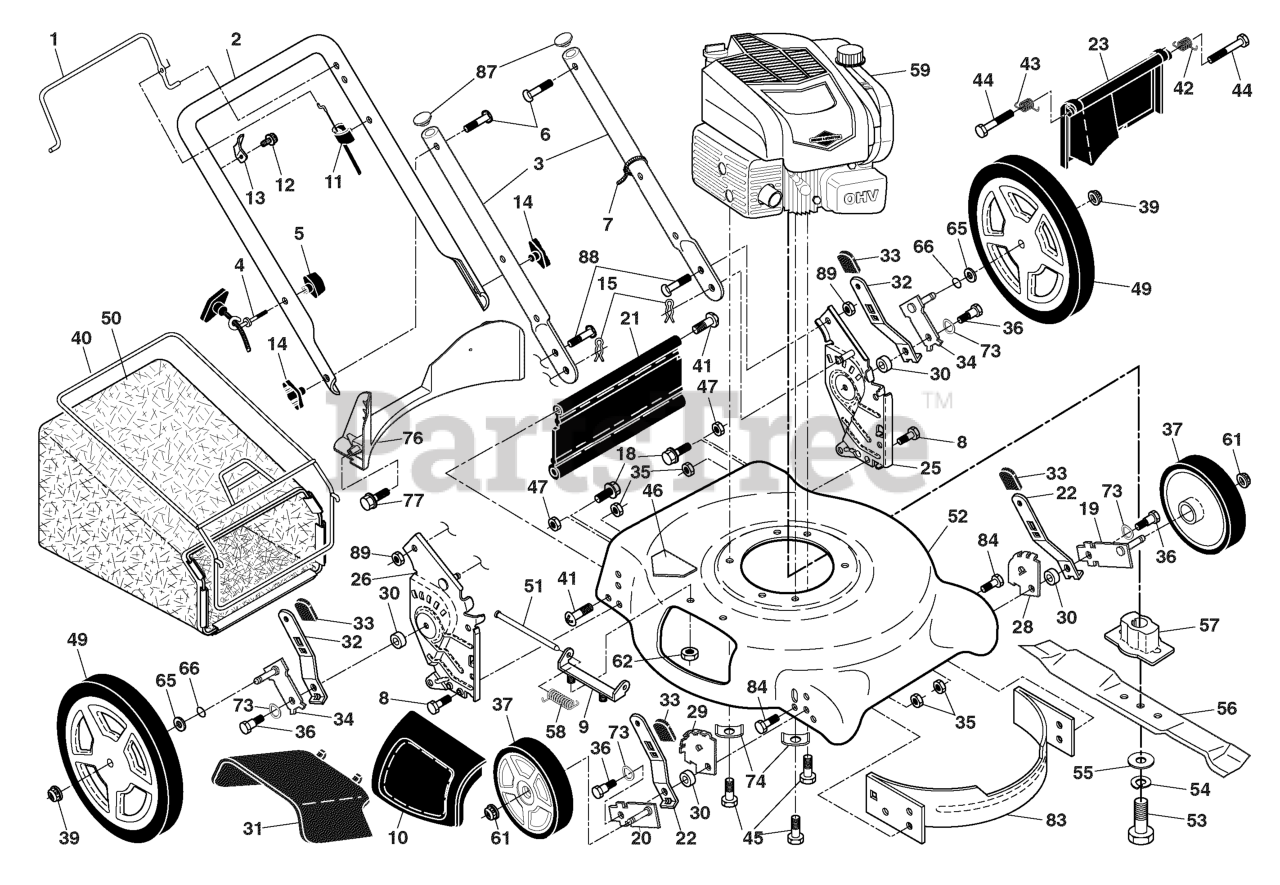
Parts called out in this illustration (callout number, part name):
1	Control Bar
2	Upper Handle
3	Bar, Lower Handle
4	GUIDE, Rope
6	Bolt, Carriage 1/4-20 x 1-1/2
7	Wire, Tie
8	Bolt, Hex Head 5/16-18 x 3/4
9	Hinge Bracket
10	Mulcher Door
11	Engine Zone Control Cable
12	SCREW, Hex Head, Threaded, Rolled, #10-16 x 5/8
13	Up-Stop Bracket
14	Knob, Handle
15	Cotter, Hairpin
18	SCREW, Hex Washer Head, 1/4-20 x 3/8
19	Axle Arm Assembly, Left Front & Right Rear
20	Axle Arm Assembly, Right Front & Left Rear
21	Kit, Rear Skirt
22	Selector Spring, Front
23	Rear Door Assembly
25	HANDLE BRACKET ASSEMBLY, Left Hand
26	HANDLE BRACKET ASSEMBLY, Right Hand
28	Wheel Adjusting Bracket, Front, LH
29	Wheel Adjusting Bracket, Front, RH
30	Spacer
31	Discharge Defl ector
32	Selector Spring, Rear
33	Knob, Selector Spring
34	HANDLE BRACKET ASSEMBLY, Right Hand
35	NUT, Hex, Flangelock 5/16-18
36	BOLT, Shoulder, 5/16-18 x .33
37	HANDLE BRACKET ASSEMBLY, Right Hand
39	Nut, Hex, Flangelock 3/8-16
40	Frame, Grass Bag
41	Screw, Hinge
42	Spring, Rear Door, LH
43	Spring, Rear Door, RH
44	Bolt, Rear Skirt
45	Screw, Hex Head, Threaded, Rolled, 3/8-16 x 1-1/5
46	Decal Deflect WRN. Cutfinger
47	Nut, Lock 5/16-18 unc
49	Wheel & Tire Assembly, Rear, 8 x 1-1-3/4
50	Grass Bag
51	Hinge Rod
52	Kit, Lawn Mower Housing
53	Screw, Machine, Hex Head, 3/8-24 x 1-3/8, Grade 8
54	Washer, Lock Hvy Hlcl Spr 3/8
55	WASHER, Hardened
56	Blade, 21"
57	Blade Adapter
58	Hinge Spring
59	ENGINE
61	NUT, Hex, Flangelock 3/8-16
62	LOCKNUT, Hex, 1/4-20
65	WASHER, Flat, 3/8
66	O-Ring
73	Washer, Curved, Cylindrical
74	Washer, Special, Engine
76	Baffle, Rear
77	Screw, Hex Washer Head, #13 x 3/4
83	Baffl e, Front
84	Screw, Hex Head 5/16-18
87	Plug, Lower Handle Bar
88	BOLT, Hex Head
89	Nut, Hex
